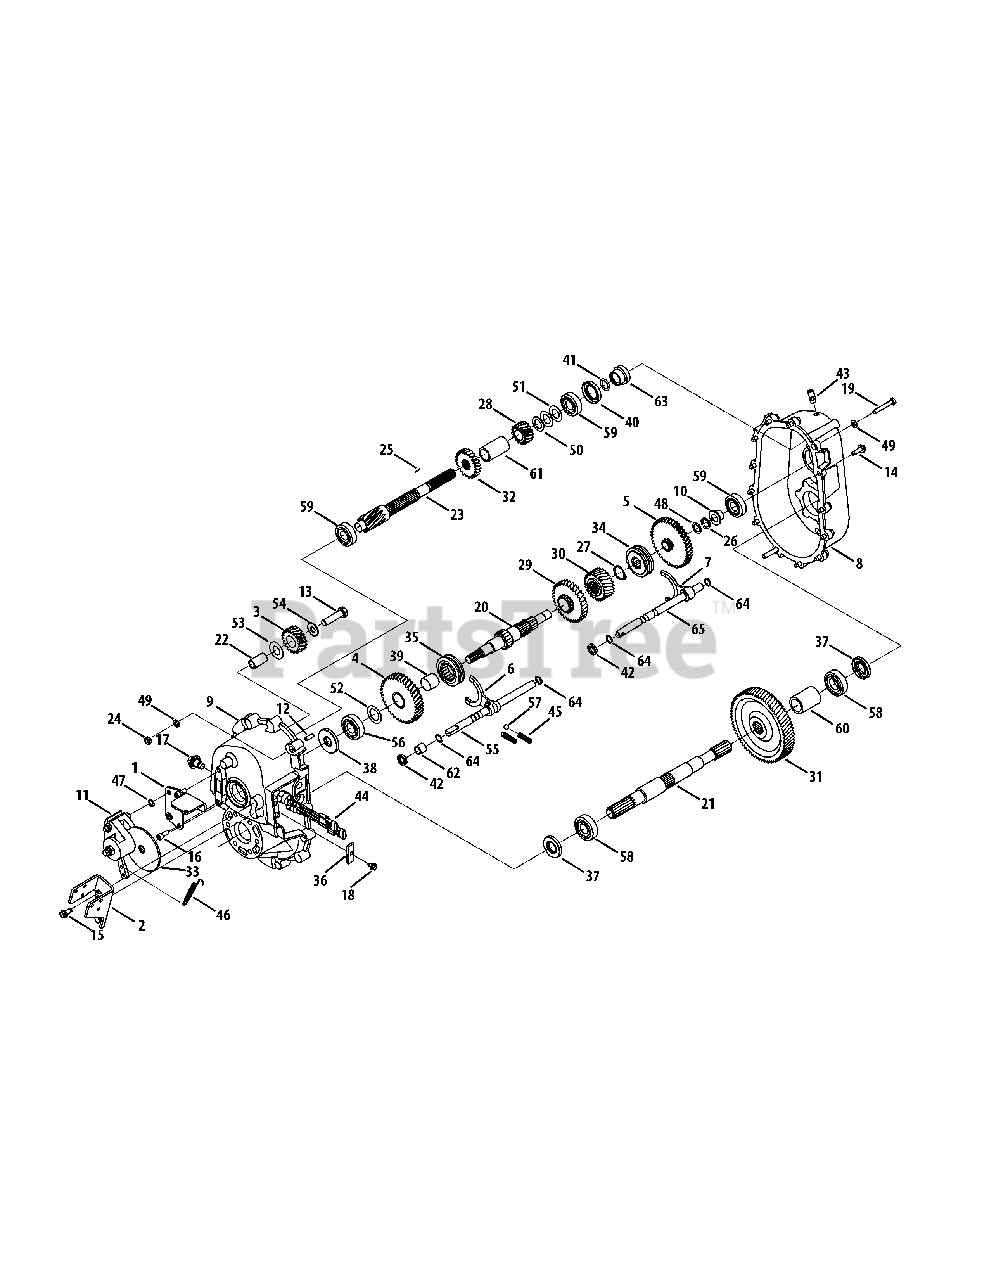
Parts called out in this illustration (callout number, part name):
1	Bracket Assembly, Painted
2	Bracket Assembly, Shift, Painted
3	Gear Assembly, Rev Idler
4	Gear, Rev, 39T
5	Gear Assembly, Low Speed
6	Yoke, Actr, Uv
7	Yoke Actr, Lo
8	Housing, Lh, Uv
9	Housing, Rh, Uv
10	Spacer, Flg, .630 x .787 x .662
11	Brake Assembly, Transfer Case
12	Dowel, Bush, .400 x .484 x .750
13	Hex Head Screw, 1/2-13, 2.00
14	Screw, Tt, 5/16-18, 1.000, Hxindwsh
15	Screw, Tt, 5/16-18, 0.750, Hxindwsh
16	Screw, Soc Hd, 5/16-18, .750
17	Screw, Plug, M14 x 1.5 x .827
18	Screw, Tt, 1/4-20 x .625, Hxindwsh
19	Hex Head Screw, 5/16-18, 2.00
20	Shaft, Mid, Transfer Case
21	Shaft, Output, Transfer Case
22	Shaft, Rev Idler
23	Shaft, Input, Transfer Case
24	Nut, Hex Lock, 5/16-18, Ctrlk
25	Pin, Roll, 1/8 Od, .63
26	External Snap Ring .625 Dia.
27	Ring, Retainer, 1.125 Dia.
28	Gear, Low Pinion, 15t
29	Gear, High, 33t
30	Gear, Final Pinion, 22t
31	Gear, Final, 73t
32	Gear, Pinion, High, 22t
33	Disc, Brk, Uv
34	Collar, Lo
35	Collar, Hi-rev, 4x4
36	Plate, Detent Spring
37	Seal, Oil, 25x46x7
38	Seal, Oil, 20x52x7
39	Bearing, 25mm x 28mm x 25mm
40	Seal, Oil, 30 x 47 x 7
41	O-ring, .734 Id x .139
42	Seal, Oil, .563 x .875 x .188
43	Creeper Drive Housing Breather
45	Spring, 3/8 Od x 1 1/4 Lg
46	Spring, Extn, .38 Od x 3.9 Lg
47	Washer, Flat, .385 x .620 x .033
48	Washer, Flat, .635x.930x.033, Ht
49	Washer, Flat, .330 x .630 x .0635
50	Washer, Flat, .793 x 1.24 x .06, Ht
51	Washer, Flat, .793x1.368x.010, Ht
52	Washer, Flat, 1.007x1.542x.03, Ht
53	Washer, Thrust, .757 x 1.38 x .062
54	Washer, Flat, .51 x 1.12 x .06, Ht
55	Shaft, Actr, Fwd, Rev
56	Bearing, Ball, .79 Id x 2.05 Od x .6
57	Ball, Detent, .375
58	Bearing, Ball, 25x52x15, 6205
59	Bearing, Ball, 20x47x14, 6204
60	Spacer, Output Shaft
61	Spacer, Mid Shaft
61	Spacer, .930 x 1.125 x 3.019
62	Spacer, .566 x .725 x .650
63	Spacer, Input, Uv, Transfer Case
65	Shaft, Actr, Lo
